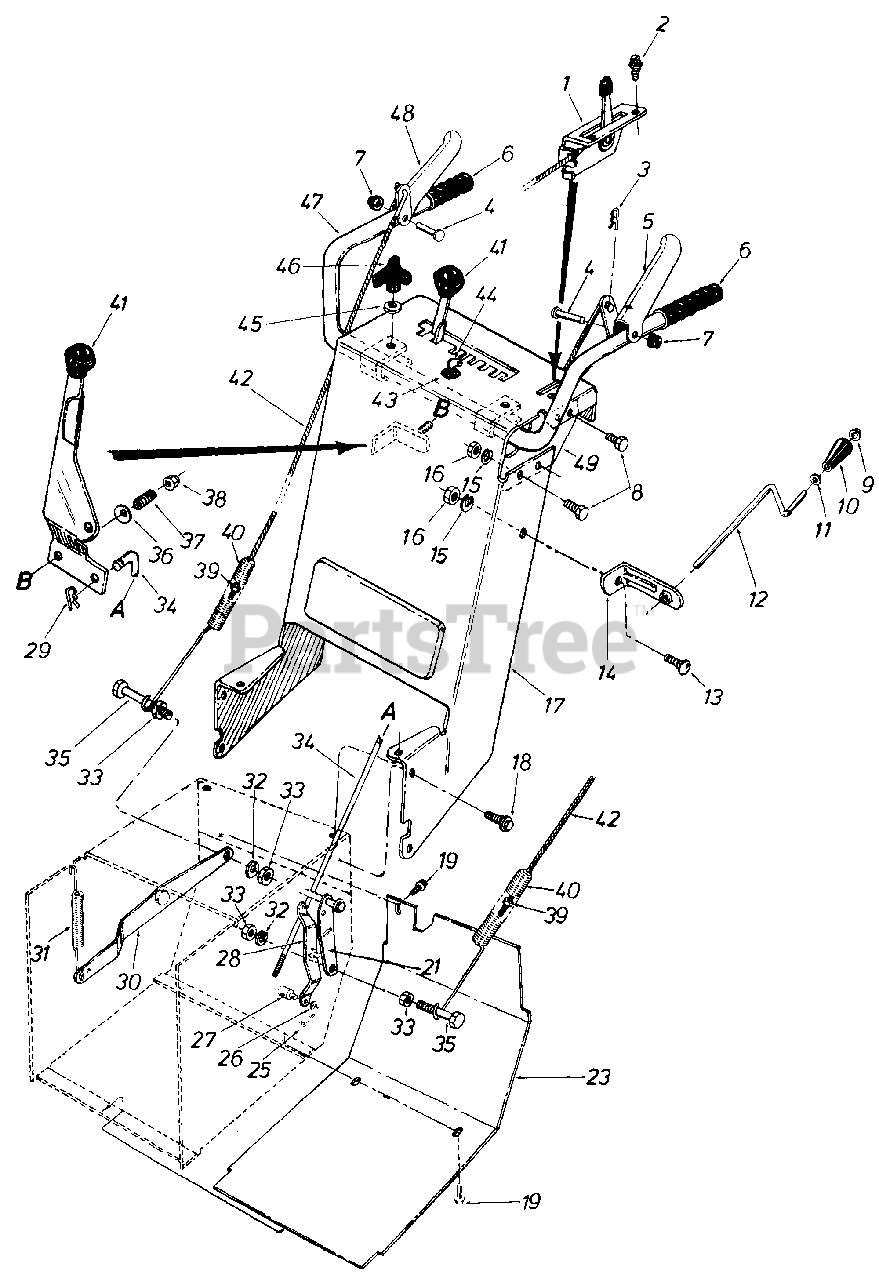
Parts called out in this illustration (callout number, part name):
1	Throttle Control Ass'y. Comp.
2	Hex Wash. Hd. AB-Tap Scr. #8 x .50
3	Hairpin Cotter 3/32" Dia. x 1.00" Lg.
4	Clevis Pin .375" Dia. x 1.88" Lg.
5	Drive Clutch Grip Ass'y. - L.H.
6	Grip Handle
7	Push Cap for 3/8" Rod
8	Hex Bolt 5/16-24 x .62" Lg.
9	Push Nut for 3/8" Rod
10	Knob w/.38" Dia. Hole
11	Fl. Wash. .385" I.D. x .62" O.D. x .063"
12	Chute Crank .38 Dia. x 35" Lg.
13	Carriage Bolt 5/16-18 x .62" Lg.
14	Chute Control Brkt.
15	L-Wash. 5/16"
16	Hex Nut 5/16-24 Thd.
17	Handle Panel Ass'y.
18	Hex Wash. Self-Tap Scr. 5/16-24 x .50" Lg.
19	Hex Wash. Self-Tap Scr. 5/16-24 x .50 Lg.
21	Drive Clutch Brkt. Ass'y.
23	Frame Cover
25	Cotter Pin 3/32" Dia. x .75" Lg.
26	Fl. Wash. .344" I.D. x .62" O.D. x .063
27	Ferrule - Engagement
28	Shifting Linkage Brkt.
29	Hairpin Cotter 3/32" Dia. x 1.00" Lg.
30	Auger Clutch Brkt.
31	Ext. Spring .38" O.D. x 3.18" Lg.
32	L-Wash. 1/4" I.D.
33	Hex Nut 1/4-28 Thd.
34	Shifting Rod
35	Hex Bolt 1/4-28 x 1.75" Lg.
36	Bell-Wash. .400 I.D. x .88 O.D. x .060
37	Comp. Spring .39 I.D. x .88
38	Hex Ins. L-Nut 3/8-24 Thd.
39	Hex Ins. L-Nut 1/4-20 Thd.
40	Spring .75" O.D. x 5.0" Lg.
41	Shift Handle Ass'y.
42	Lock-Out Cable 30.5" Lg.
43	Ignition Switch
44	Ignition Key
45	Bell-Wash. .345 I.D. x .88 O.D. x .060
46	Three Arm Knob - 5/16-18 Thd.
47	Handle Ass'y.
48	Auger Clutch Grip Ass'y. - R.H.
49	Handle Support Brkt.
